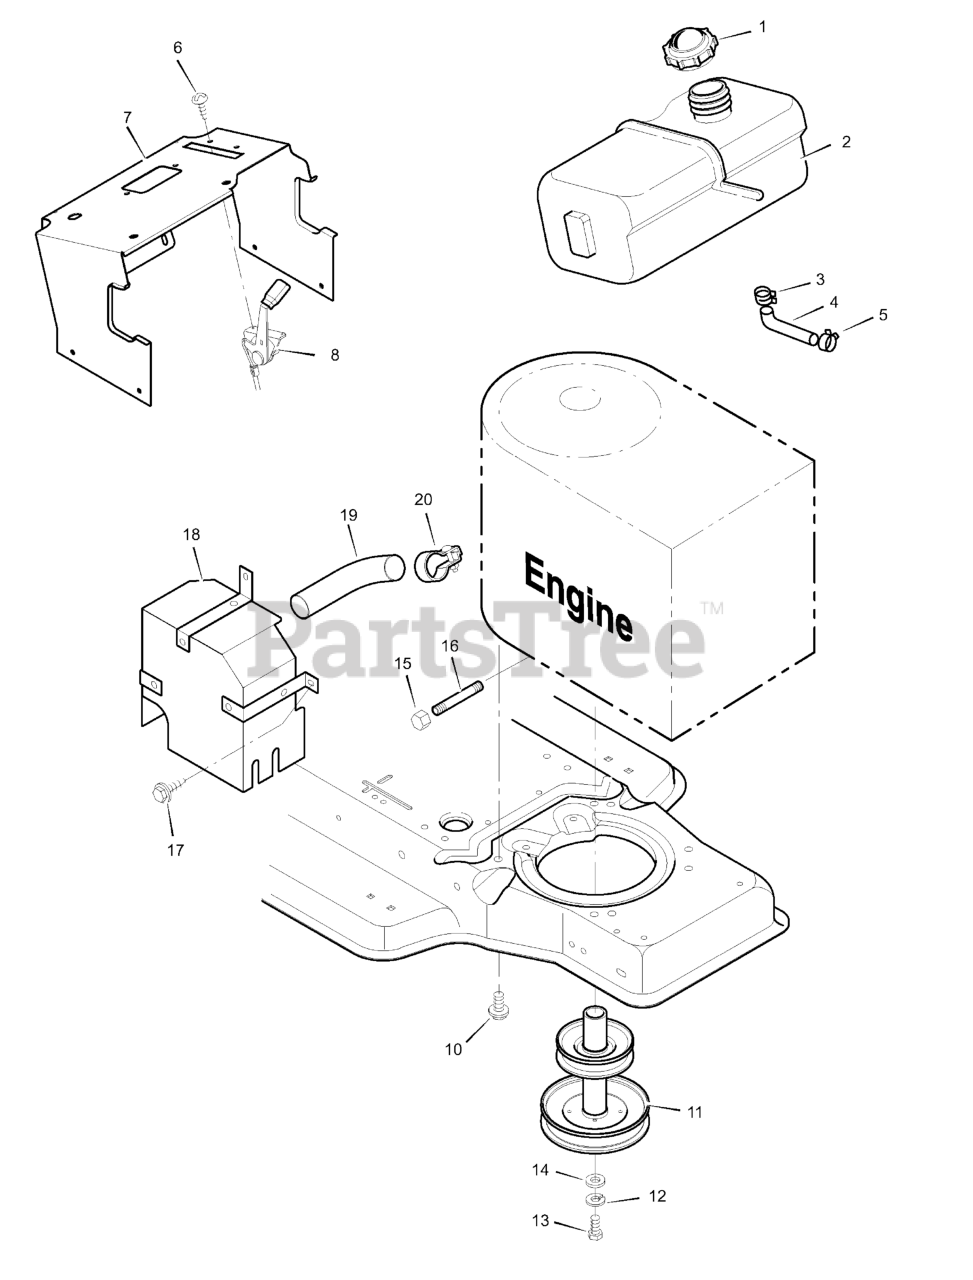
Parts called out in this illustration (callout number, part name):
1	Fuel Cap
2	Fuel Tank
3	Hose Clamp
4	Fuel Line
5	Hose Clamp
7	Support, Dash
8	Throttle Control
9	Engine *
10	Bolt, Engine Mount
11	Stack Pulley Assembly
12	Lockwasher
13	Bolt, Hex
15	Cap, Oil Drain
16	Pipe, Oil Drain
18	Shield, Heat
19	Pipe, Exhaust
